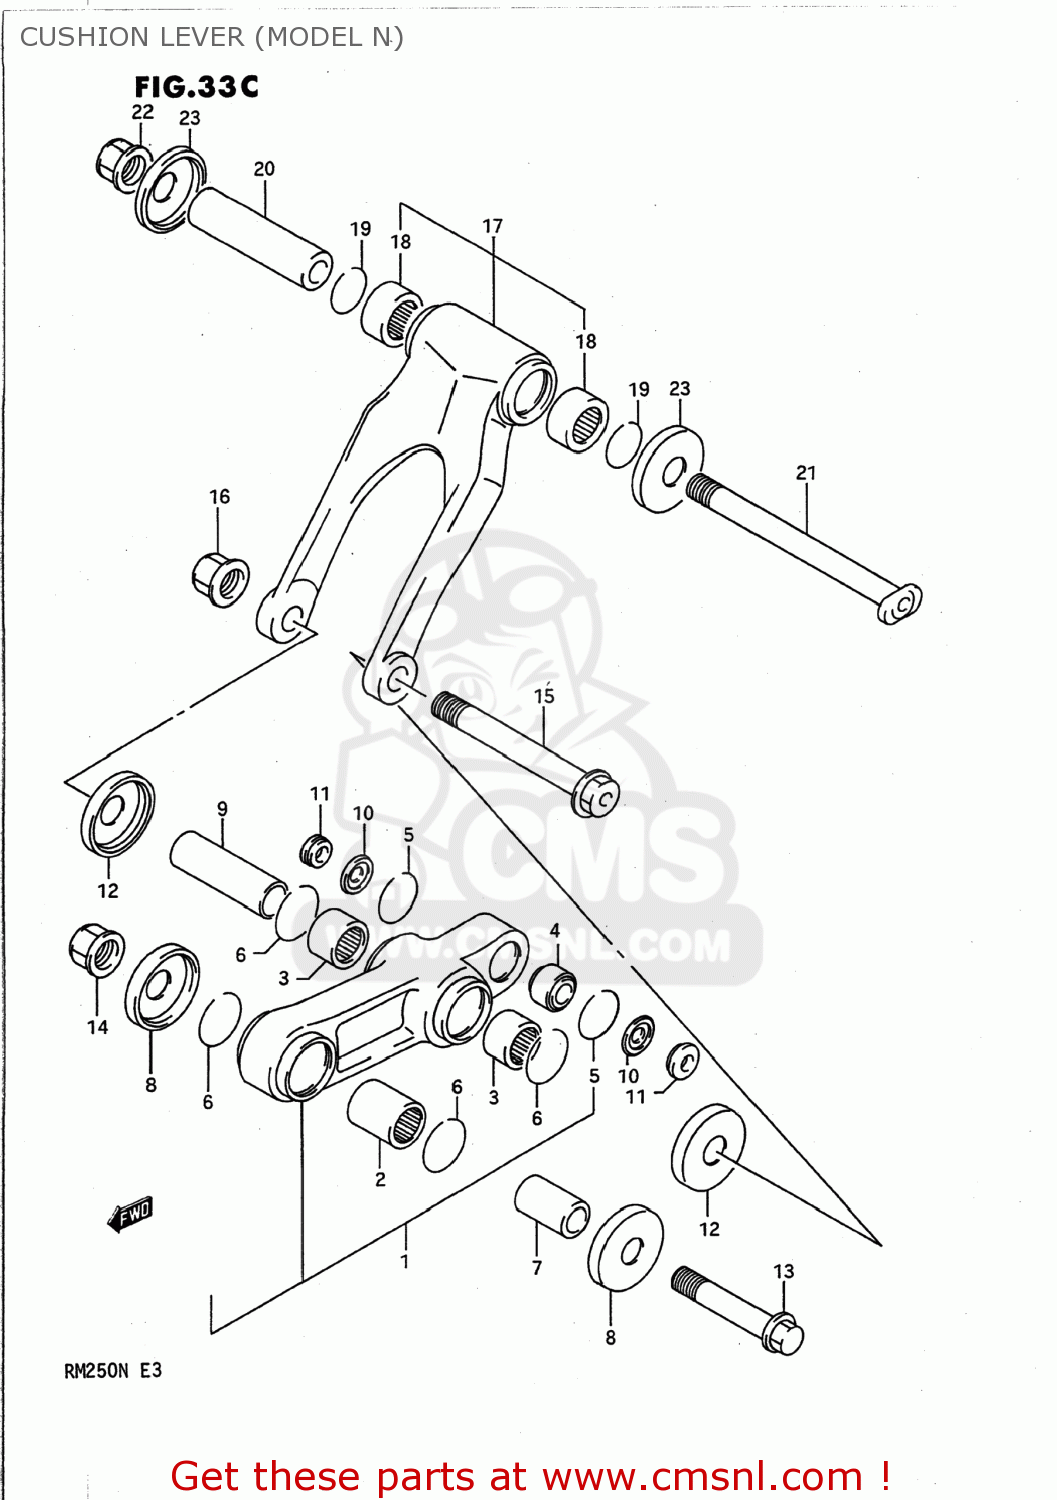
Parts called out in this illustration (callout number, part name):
1	LEVER SET,REAR CUSHION
2	BEARING(20X27X25)
3	BEARING(21X27X20)
4	BEARING,RR CUSHION LEVER RR
5	RING,BEARING STOPPER
6	CIRCLIP
7	SPACER,RR CUSHION LEVER FR
8	SEAL,REAR CUSHION LEVER
9	SPACER,REAR CUSHION LEVER,C
10	SEAL,RR CUSHION LEVER RR DUST
11	SPACER,RR CUSHION LEVER RR
12	SEAL,REAR CUSHION LEVER
13	BOLT,RR CUSHION LEVER FR
14	NUT 12MM
15	BOLT,RR CUSHION LEVER CTR
16	NUT
17	LEVER SET,REAR CUSHION
18	BEARING(21X27X20)
19	CIRCLIP
20	SPACER,RR CUSHION ROD
21	BOLT,RR CUSHION ROD
22	NUT
23	SEAL,REAR CUSHION LEVER
